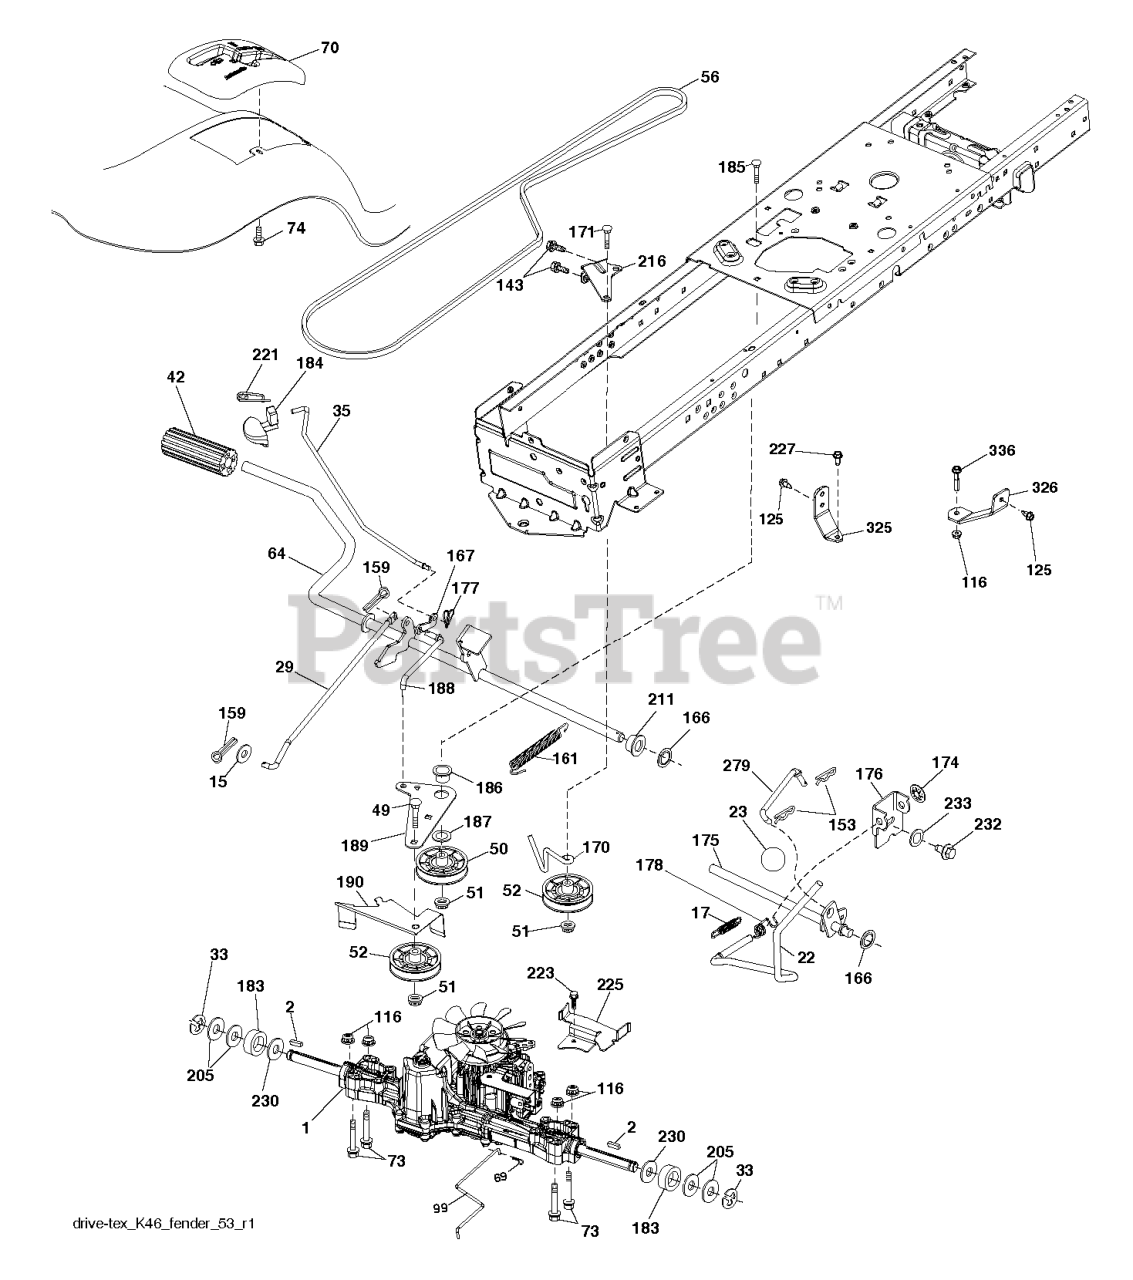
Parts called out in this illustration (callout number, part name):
2	SQUARE KEY
15	WASHER PLAIN WASHER 3/8 X 0.08
17	SPRING.BRAKE.K46.GREEN
22	ROD.SHIFT.FENDER.TLT.2006
23	KNOB.DELUXE.(PISTOL.GRIP).BLAC
29	ROD.BRAKE.K46
35	ROD ROD.PARKINGBRAKE.GT.HUSQ/P
42	PEDAL COVER
50	IDLER.FLAT.910.OFFSET
51	NUT LOCK FLG 3/8-16 UNC
52	IDLER.V-GROOVE.910.OFFSET
64	SHAFT.ASM.PEDAL.BRAKE.
69	HAIRPIN.SOFT.ZINC.059X1.125
70	CONSOLE.SHIFT.STL.HYD.TEX.GREY
99	ARM.PIVOTING.TCRD.GEN2.5.BAGGE
125	SCREW
153	RETAINER M
161	SPRING, RETURN LT
166	NUT.PUSH.625
167	LATCH.BRAKE.SPRING
170	KEEPER.V-IDLER.CENTER.
174	NUT.PUSH.500.2006
175	SHAFT ASM SHIFT
176	ARM.CLEVIS.ROD.SHIFT
177	PIN COTTER;LOCKING;BOWTIE;1IN
178	SPRING.SHIFT.GT2006
183	SPACER AXLE
184	HANDLE.PARKING.BRAKE.H (BLK)
186	SPACER.RETAINER
188	LINK.CLUTCH.GROUND DRIVE.LONG
189	BELLCRANK.GROUND.DRIVE.TEX.
190	KEEPER.BELLCRANK.DRIVE
211	BUSHING.SHAFT.BRAKE.HAND
216	BRACKET.PULLEY.IDLER.W/TEX
221	RETAINER.SPRING.CLIP.H
225	KEEPER.BELT.TRANSAXLE.K46
230	WASHER.HARDENED
279	LINK.SHIFT.T/A.K46.FEND.TX
325	BRACKET.TRQ.STP.46.20".TIRE.LH
326	BRCKT.PNT.TRQ.STP.46.20TIRE.RH
